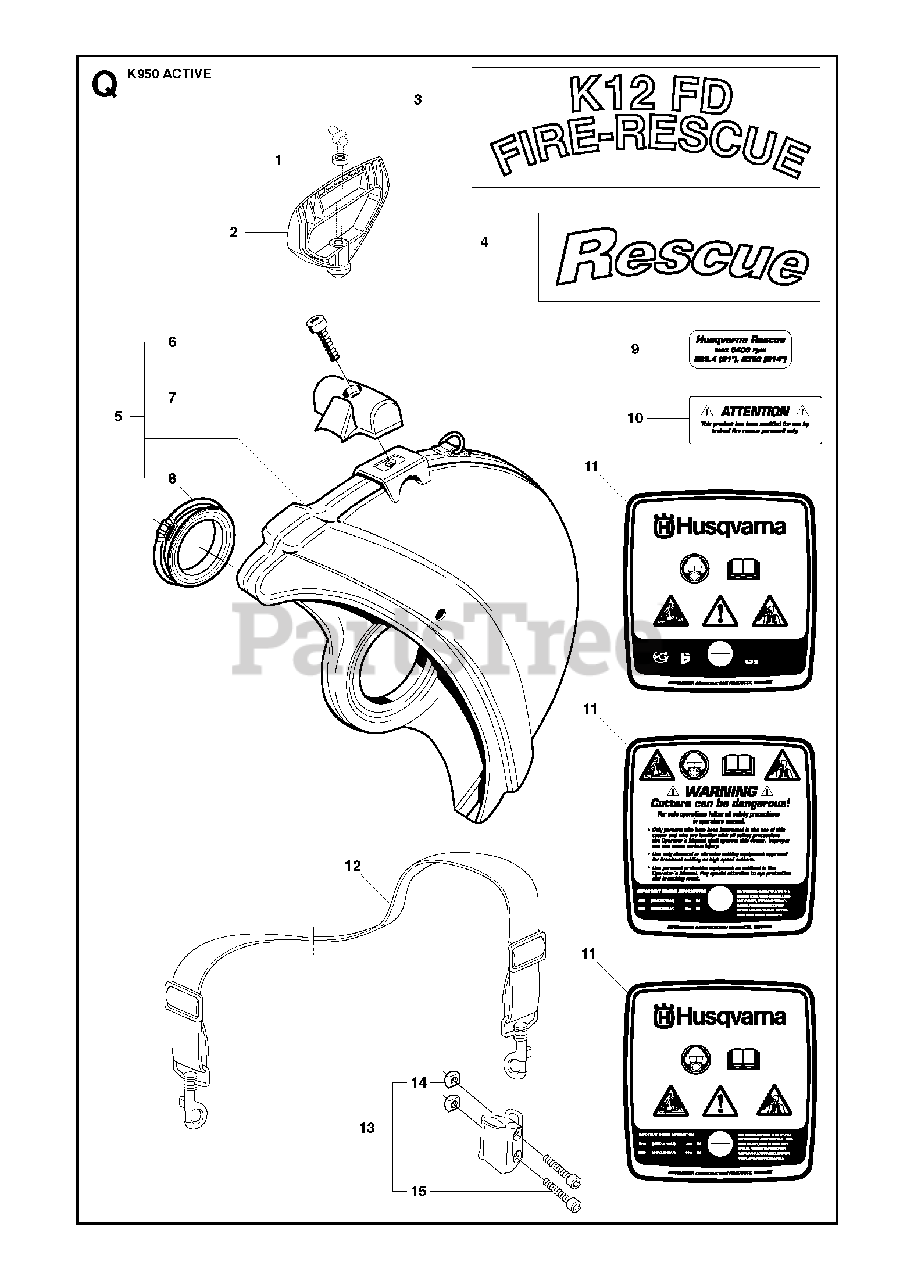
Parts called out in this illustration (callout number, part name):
5	WHEEL GUARD ASSY"Rescue 14"". Incl. 6, 7, 8"
6	SCREW IHSCM
11	LABELEPA USA
11	LABELEPA Canada
12	SHOULDER STRAP
15	SCREW IHSCFM
